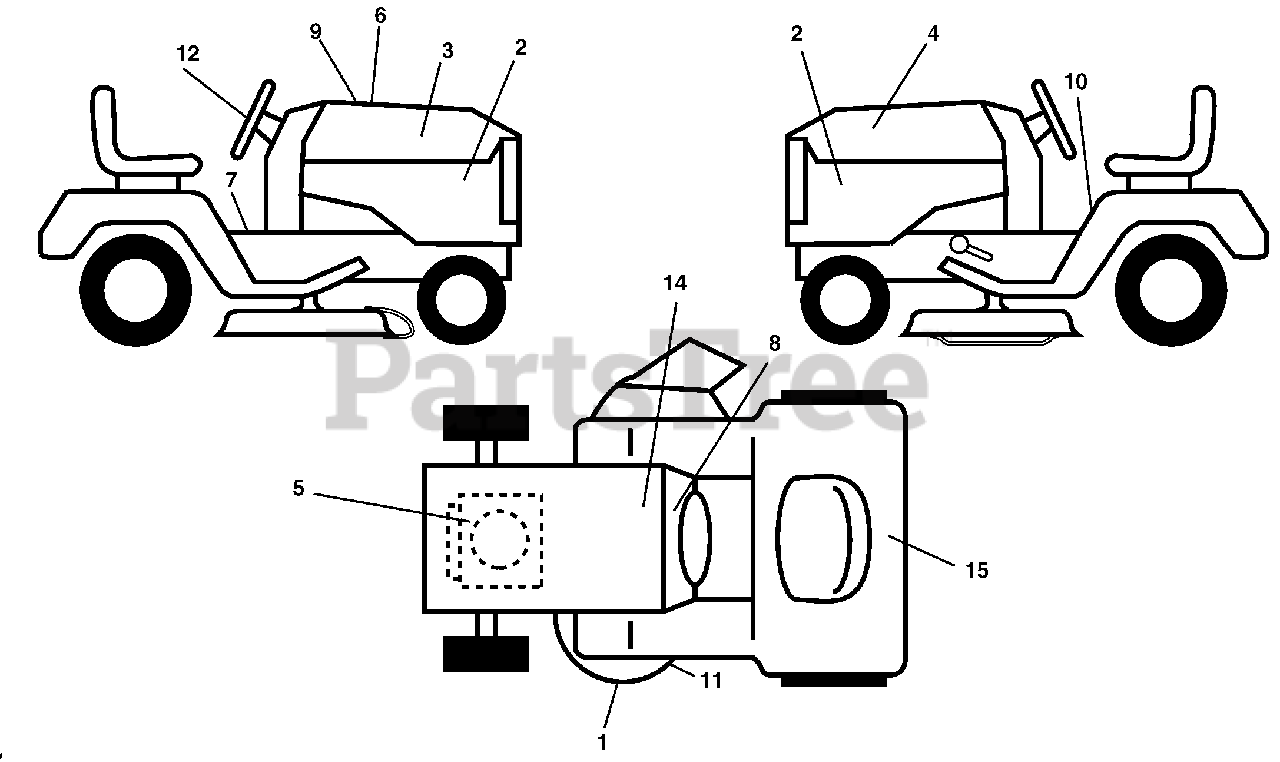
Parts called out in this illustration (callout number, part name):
1	Decal Deck Hvy Duty
2	Decal Panel Side
3	Decal Hood RH
4	Decal Hood LH
5	Decal HP Engine
6	Decal Hood Cust. Resp.
7	Decal Operator
8	Decal Dash
9	Decal Replacement
10	Decal Fender Danger
11	Decal V-Belt Sch.
12	Decal Wheel Steering
14	Decal Bat Dan/Psn
15	Decal Fender
